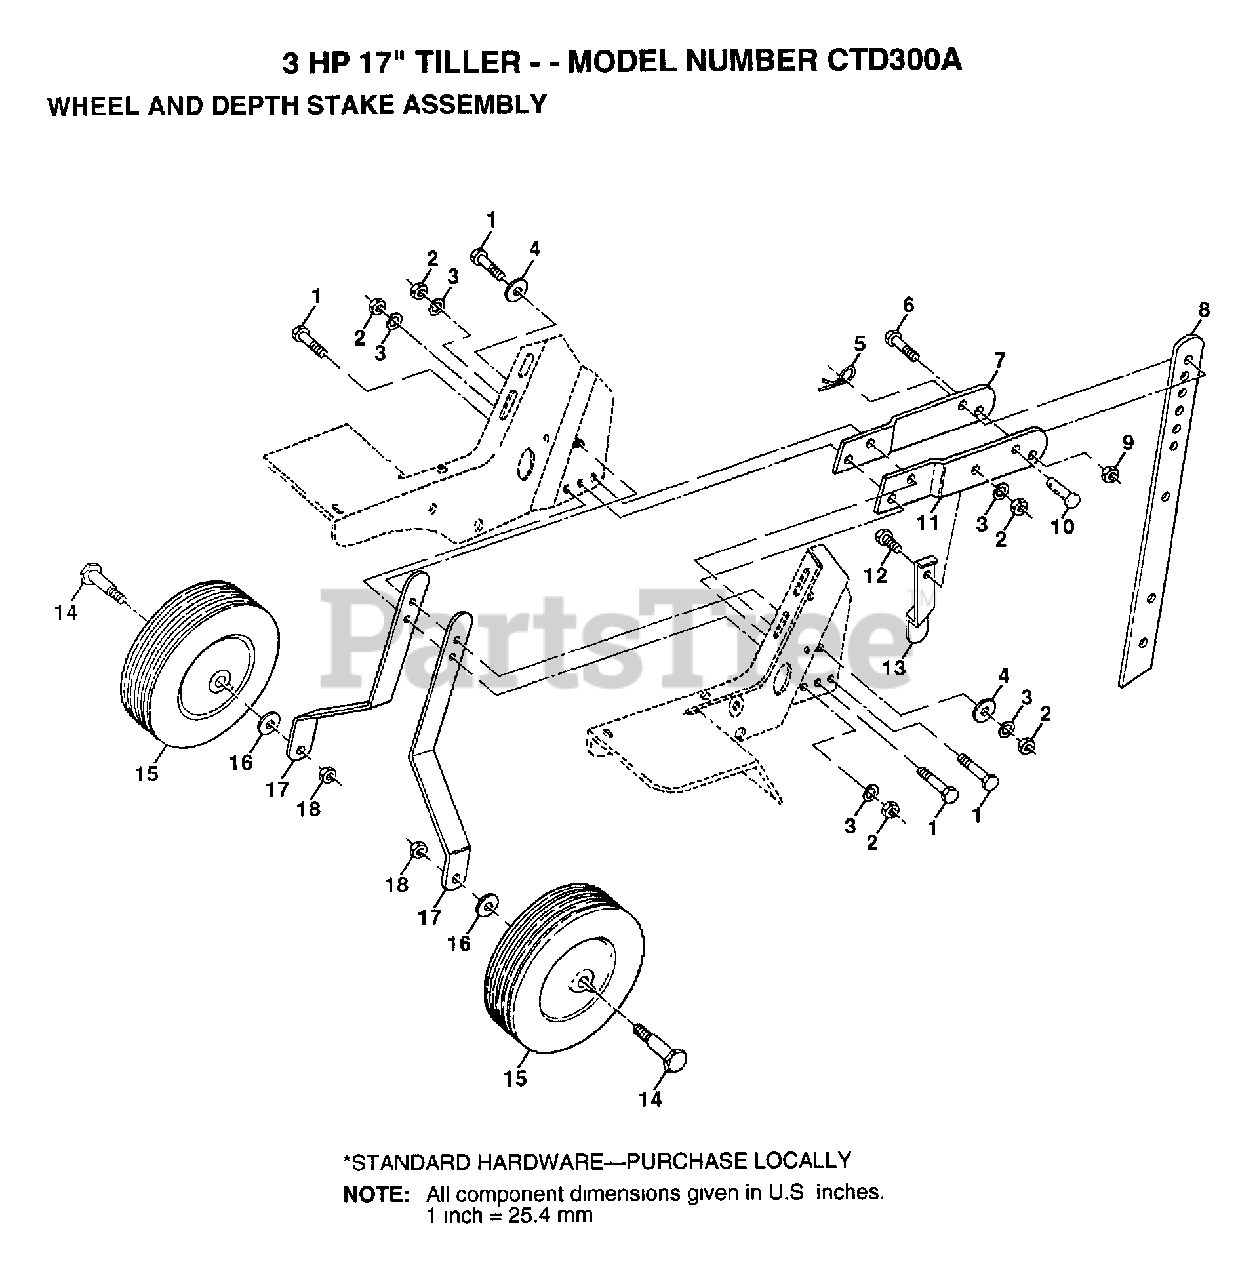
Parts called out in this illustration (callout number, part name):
2	NUT.HEX.5/16-18
3	LOCKWASHER
4	WASHER
5	SPRING.RETAINER
6	BOLT.3/8-24X1-1/2
7	STAKE.SUPT.TILLER
9	GRIPCO NUT
10	DRILLED RIVET RT
12	BOLT
13	STAKE SPRING CT
14	BOLT SHOULDER
16	WASHER
